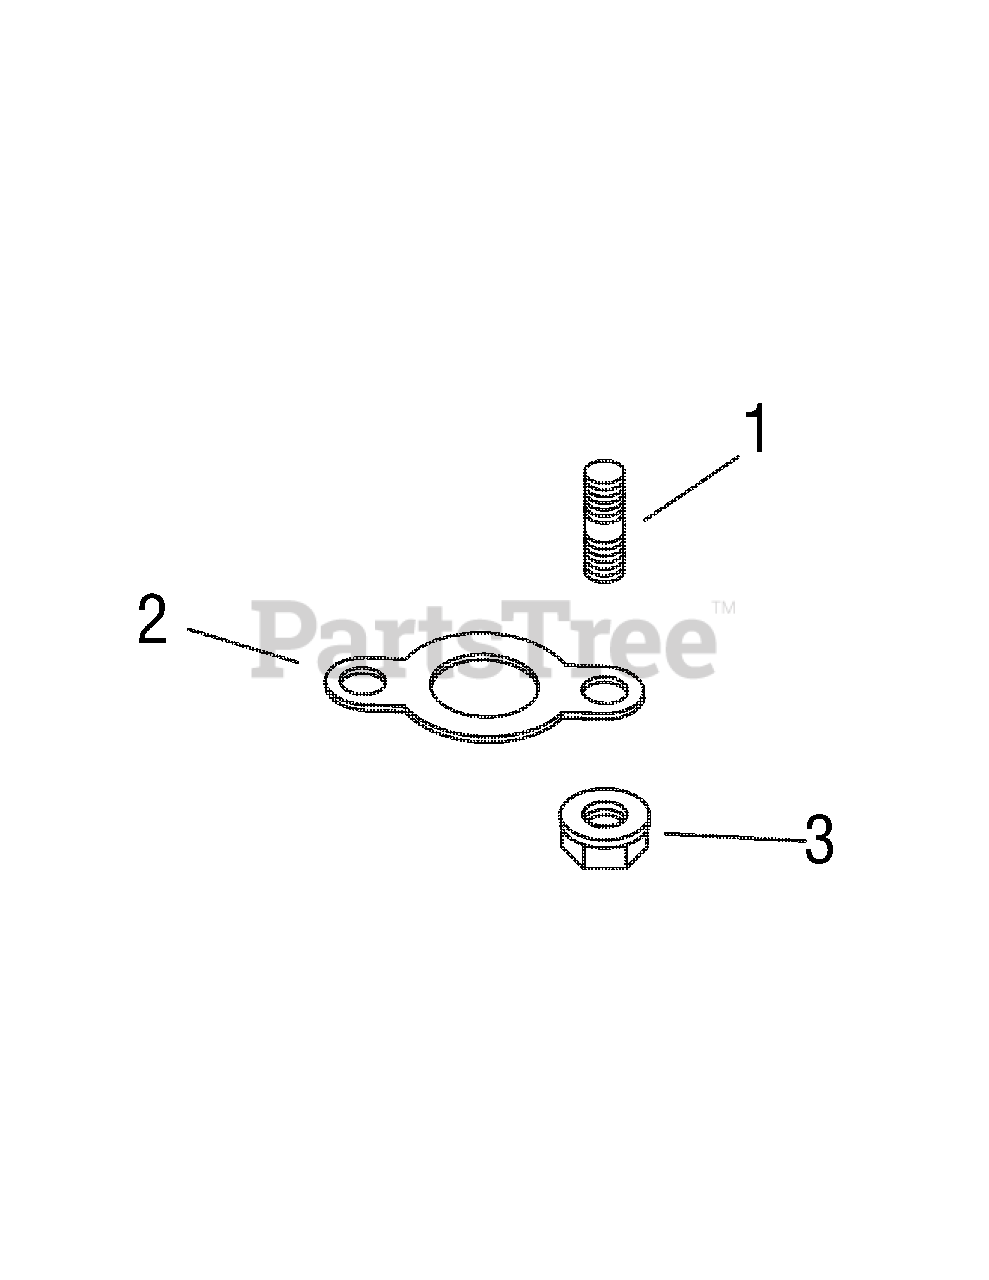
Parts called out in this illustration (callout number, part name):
1	Stud, M8x1.25x33
2	Gasket, exhaust manifold
3	Nut, hex. flange M8x1.25
